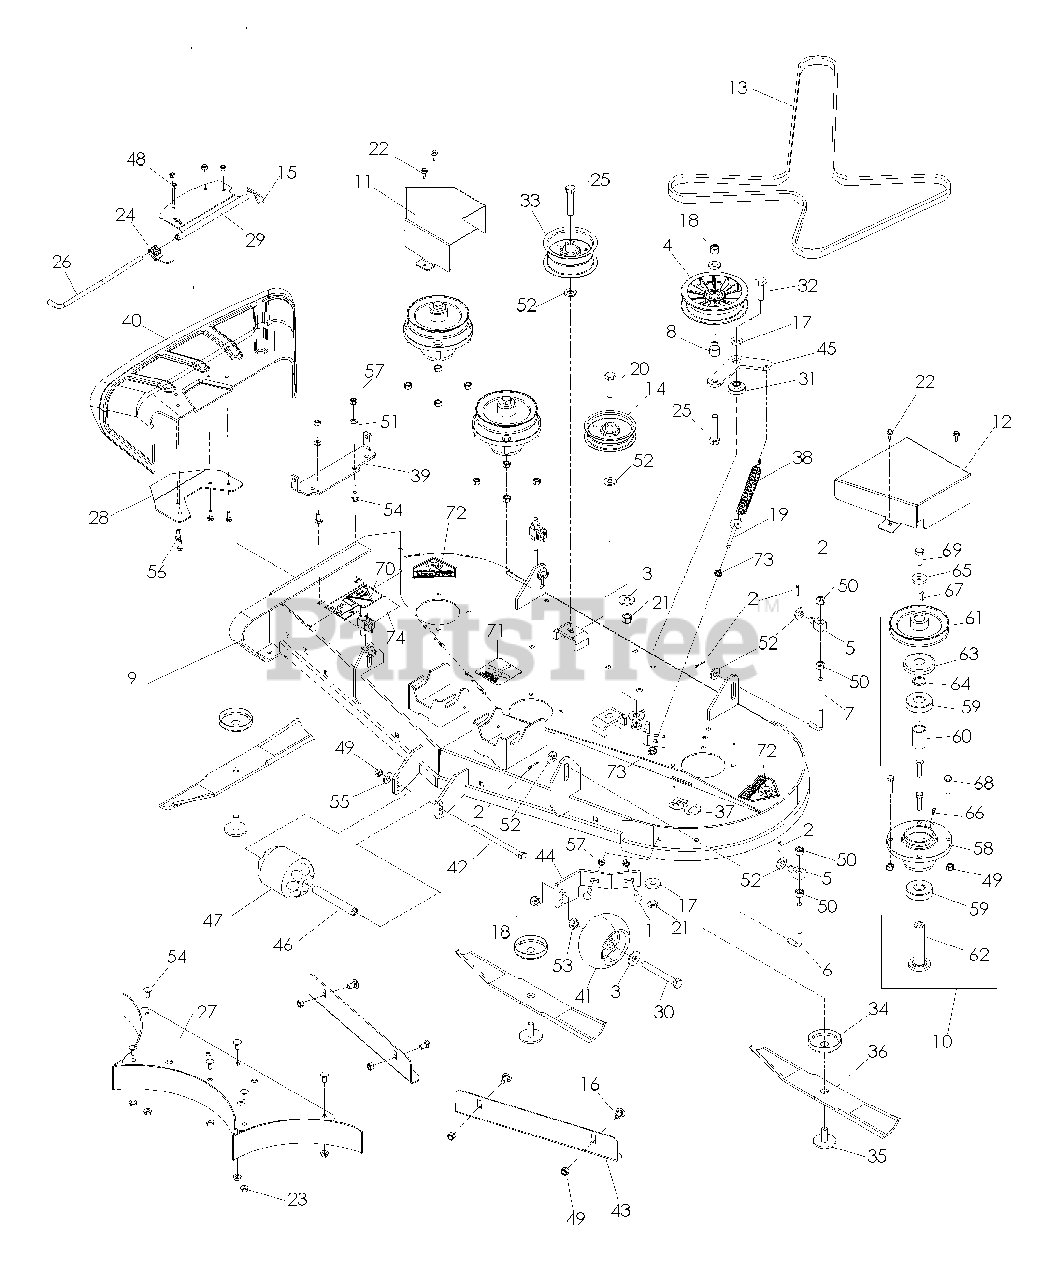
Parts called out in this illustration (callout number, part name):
1	RHSSNB 5/16C X 1.0
2	COTTER PIN 1/8 X 3/4
3	WASH USS FLAT 1/2
4	PULLEY, IDLER
6	L BOLT, S
7	L BOLT, L
8	SPACER - IDLER
9	DECK W/DECAL 50" RAM
10	SPINDLE, LH 6305 BRG
11	PULLEY GUARD RH BLACK
12	PULLEY GUARD LH
13	V-BELT 170" B
14	PULLEY IDLER
15	PIN, COTTER 1 3/4
16	RHSNB 3/8-16 X 3/4 GR5 ZD
17	WASHER-.533IDX1.37OD
18	NUT 1/2-13 HEX NYLOC ZD
19	EYE BOLT 5/16 X 3.50
20	BOLT 1/2-13 X 2 HH
21	NUT, 1/2-13 THIN PROF NYL
22	SCREW, TAP & DR #12-14 X 3/4
23	5/16-18 FLANGED L-NUT
24	SPRING, TORSION
25	1/2-13X2-1/2 HHB GR5
26	DEFLECTOR PIN
27	W-BAFFLE WLDT.
28	DEFLECTOR BRACKET
29	DEFLECTOR MT BRKT
30	HCS 1/2-13 X 4 GR 5 ZD
31	IDLER SPACER
32	1/2-13X1-3/4 HHB GR. 5
33	IDLER PULLEY
34	TRASH GUARD
35	BLADE BOLT
36	BLD 50`HI LIFT FUSION
37	DECAL, DECK 50"
38	SPRING, DECK BELT
40	44 DEFLECTOR
41	GAUGE WHEEL
42	BOLT 3/8 X 6 GR5
43	BLOW-BY BAFFLE
44	BRACKET
45	IDLER ARM
46	BUSHING
47	ROLLER 3-3/4 DIA. X 4-1
48	NUT 1/4-20 NYLOC
49	NUT 3/8-16 NYLOC
50	NUT 7/16C HEX
51	FLAT WASHER 5/16 SAE
52	WASHER 1/2" FLAT
53	NUT HEX 1/2
54	BOLT 5/16C X 3/4" CARRIAGE
55	WASHER 3/8 FLAT
56	HCS 1/4C X 3/4 HCS
57	NUT 5/16 NYLOC
58	DECK HUB MACHINED
59	BEARING - 6305 - 2RS
61	METRIC PULLEY
62	SHAFT SHORT
63	TRASH GUARD
64	HUB PULLEY SPACER
65	WASHER .525 X 1.375 X .25
66	ZERK, 3/16, DRIVE IN
67	OUTER SHAFT KEY
68	HHB 3/8-16X1-1/2 GR5
69	1/2-20 UNF X 1 1/4 HHBLT
70	DECAL, EURO SEVERING
71	DECAL, BELT ROUTING (18656)
72	DECAL, CPSC
73	NUT 5/16C WHIZ
74	DECAL, DANGER
